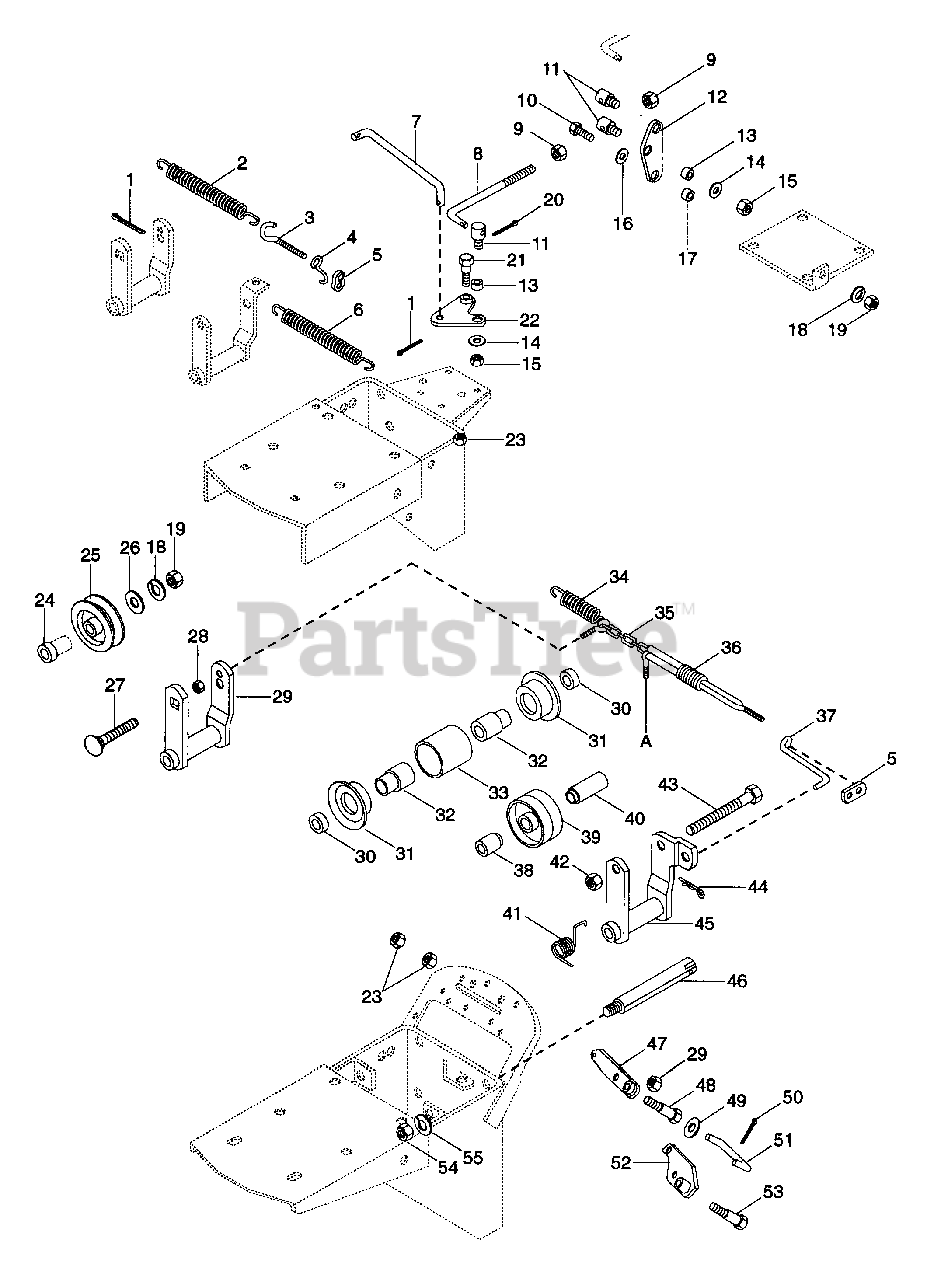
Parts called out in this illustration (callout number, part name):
1	PIN-COTR .12X1.0 PL
2	SG-TENS .105X.812X3.88 WLD 15
3	EYE BOLT
4	LINK-CLUTCH
5	RETAINING NUT
6	SG-TENS .063X.44X2.81 WLD 18
7	CROSS LINK
8	ROD
9	NUT-JAM .375-16 PL
10	BLT-HEX .31-18X1.00 PL GR 2
11	UNIVERSAL ROD ADAPTER
12	ARM
13	SPACER .63 X .50 X .18
14	WSHR-FL-STL .505X1.000X.062
15	NUT-LK-CTR .50-13
16	WSHR-FL-STL .390X.750X.125 PL
17	SPACER BUSHING .5 X .32 X .21
18	WSHR-LK .312X.097 PL HVY
19	NUT-HEX .312-18
20	PIN-COTR .15 X 1.0 PL
21	BLT.SHLDR .38-16 X 1.25
22	PIVOT LEVER
23	NUT-LK-CTR .375-16 GR A PL
24	BEARING SPACER
24	SPCR, BRG .315X.50X.688X.281
25	IDLER
26	WSHR-FL-STL .38X.875X.083 PL
27	BLT-RDHDSQNK .31-18X1.38SHT PL
28	NUT-LK 8-32 GR A PL
29	IDLER ARM
29	REVERSE IDLER ARM
30	BSHG, SPCR.500X.750X.321 PM
31	IDLER
32	BEARING SPACER
33	SLEEVE
34	SG-TENS .039X.44X1.75 WLD 3.2
35	CLUTCH CHAIN
36	CLUTCH SPRING
37	CLUTCH LINK
38	SPACER .328X.625X.843
39	IDLER-FLAT 2.25 X .38
40	SPACER-SHOULDER
41	SG-TORS .076X.89X1.98
42	NUT-LK .312-18 GR A PL
43	BLT-HEX .31-18X3.75 PL GR2
43	BLT-HEX .31-18X4.00 PL GR2
44	PIN-HAIR INT .06X.18X.77
45	IDLER ARM
46	IDLER PIN
47	SPRING ARM
48	SHOULDER BOLT
49	WSHR-FL-STL .328X.875X.062 PL
50	PIN-COTR .09X1.0 PL
51	CLUTCH LINK
52	CLUTCH BELLCRANK
53	SHOULDER BOLT
54	NUT-HEX .375-16
55	WSHR-LK .375X.094 MED PL
